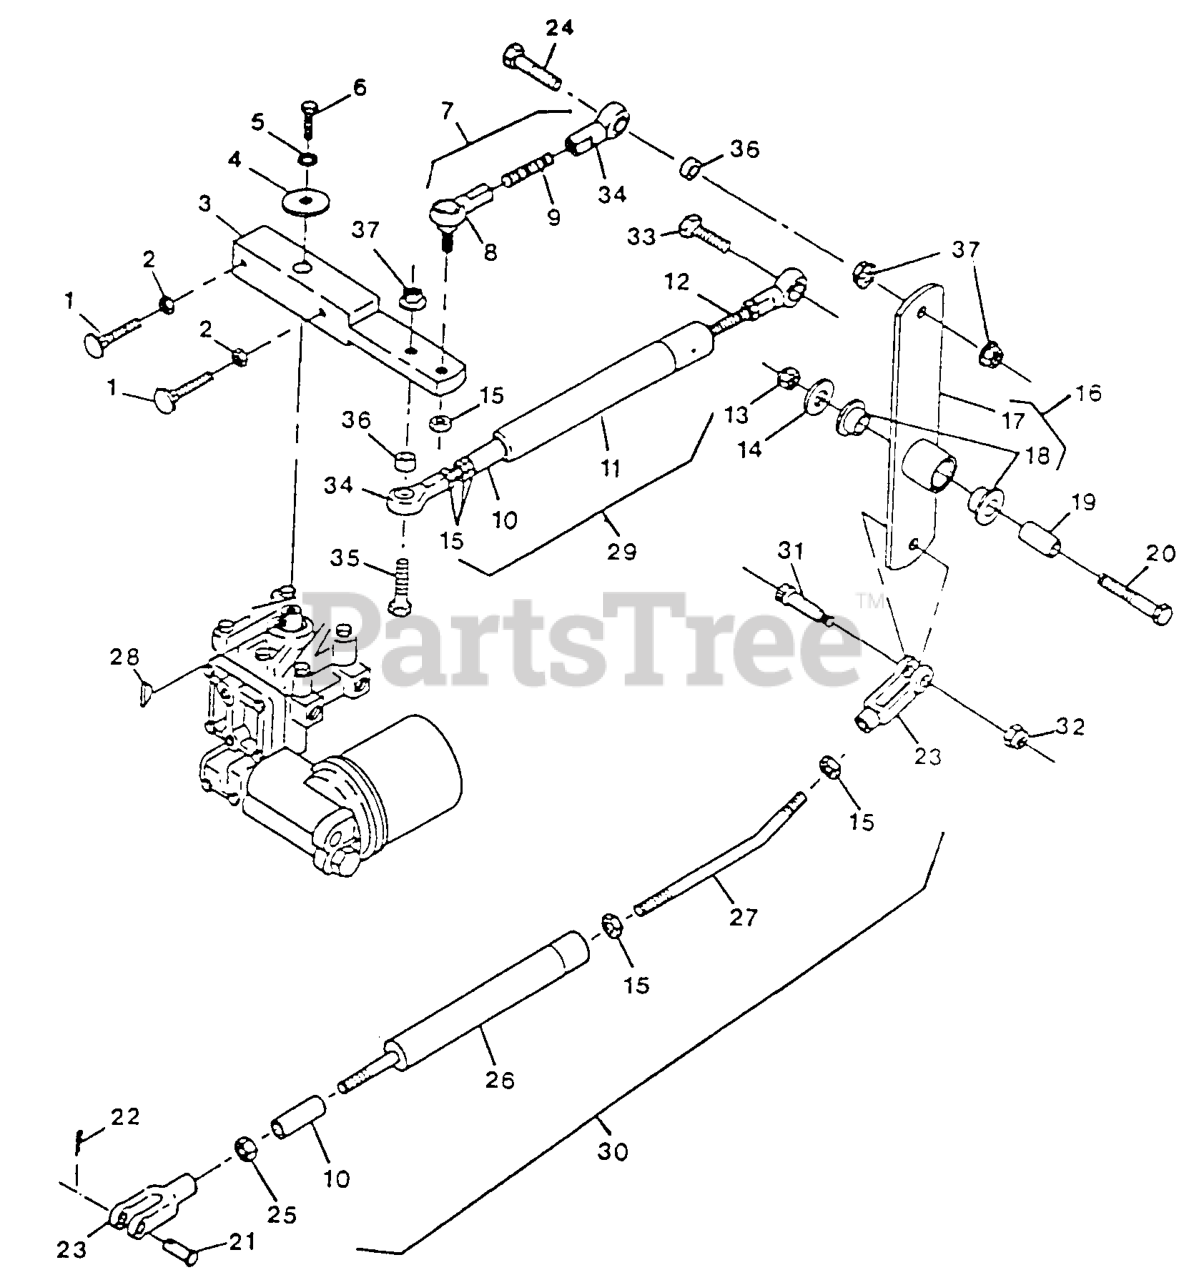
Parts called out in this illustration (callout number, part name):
3	WLD,ARM TRANSAXLT
4	WASHER-RETAINER, PULLEY
5	WASHER-LOCK
6	Capscrew, 1/4-20 X 1-1/2
8	BALLJOINT
9	ROD END PLTD.
10	BUSHING,SPRING GUIDE
12	ROD,END
17	WLD,IDLER LINKAGE
18	BEARING-CONTROL
19	BUSHING,MOTION LEVER
21	PIN-CLEVIS
23	YOKE-ADJUSTABLE
27	LINKAGE,ROD
30	ASM,PEDAL OVERRIDE
31	SCREW-HSH
34	BALLJOINT-RH
36	SPACER-PLATED
